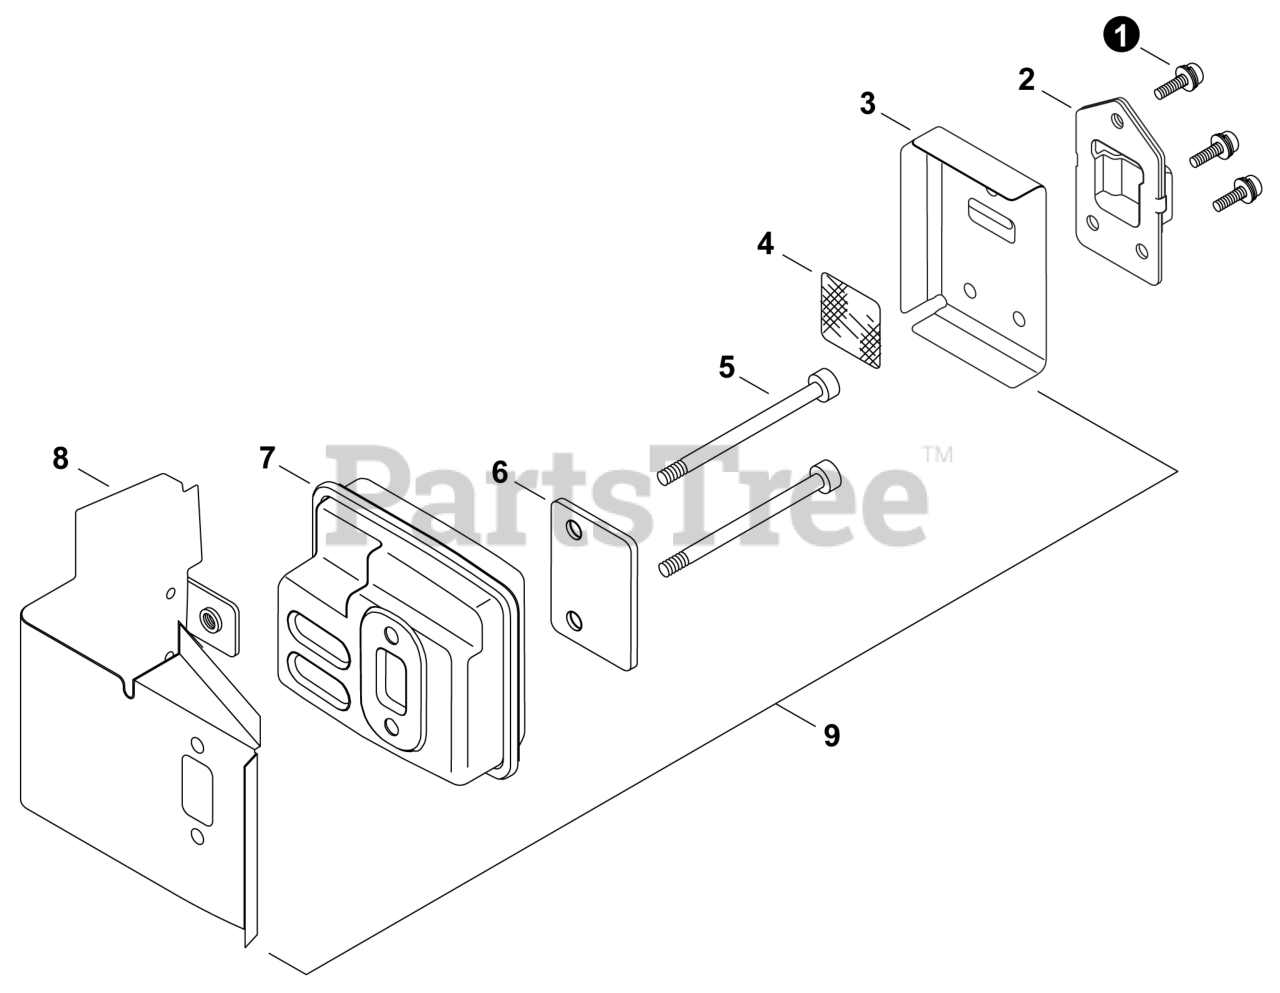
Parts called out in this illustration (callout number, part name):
1	SCREW 4x10
2	GUIDE, EXHAUST
3	GASKET, EXHAUST
4	SCREEN, SPARK ARRESTER
5	BOLT 5x55
6	PLATE, EYE
7	MUFFLER
8	HEAT SHIELD, EXHAUST
9	GASKET KIT: ENGINE, INTAKE, EXHAUST
